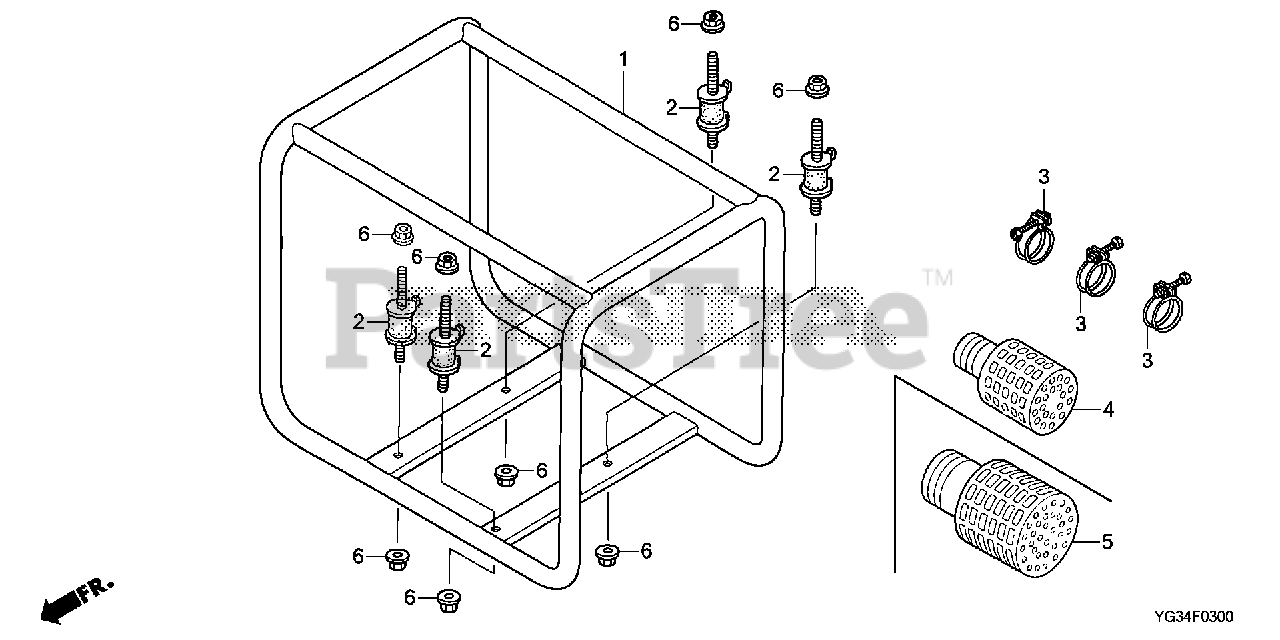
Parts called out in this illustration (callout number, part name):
2	RUBBER, ENGINE MOUNTING
3	BAND, HOSE
6	NUT, FLANGE (8MM)
